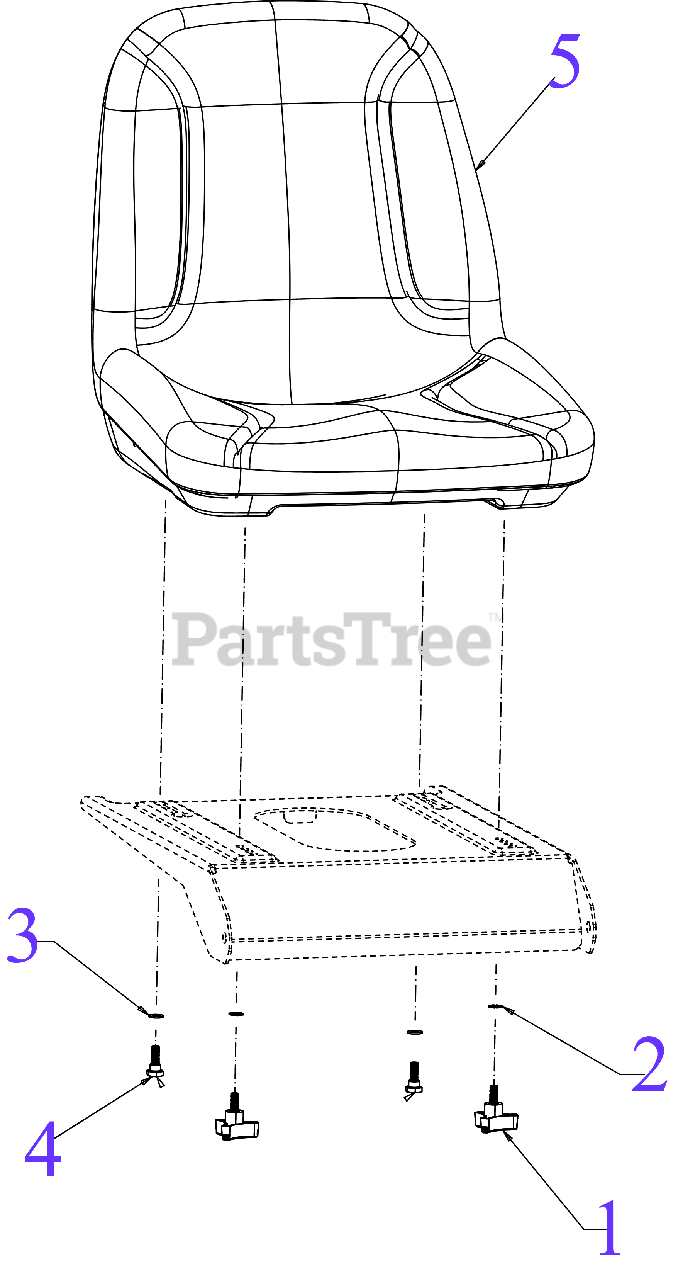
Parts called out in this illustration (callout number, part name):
1	3 PRONG KNOB 5/16-18
2	WASHER
3	FLAT WASHER ID-.320 x .598
4	SHOULDER SCREW .437 DIA x .265
5	18" SEAT 4 PT MOUNT
